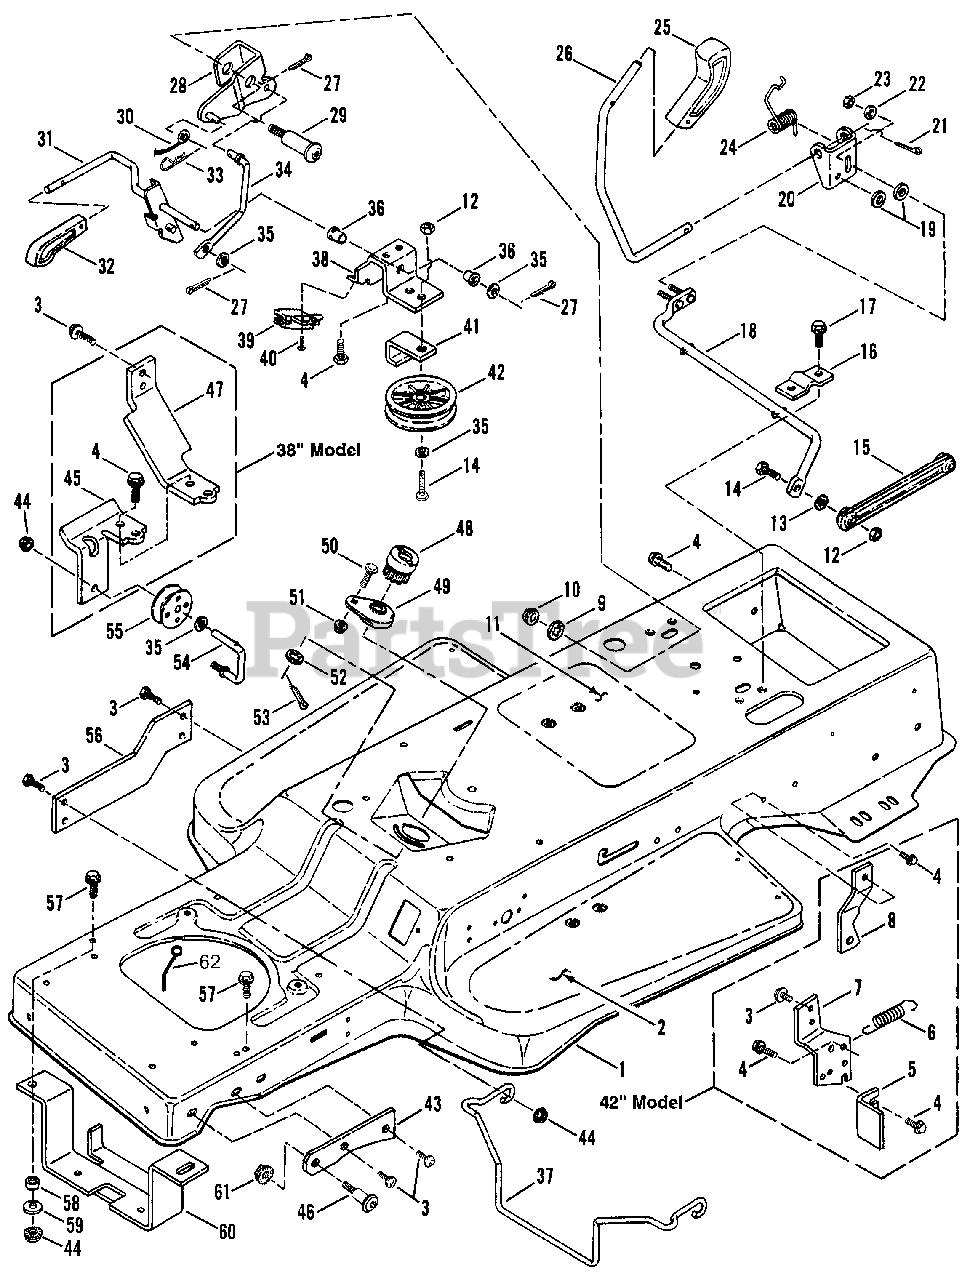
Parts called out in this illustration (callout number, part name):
1	FRAME, Blackhawk Tractor
2	FOOTPAD, Sandpaper
2	FOOTPAD, Deluxe
3	SCREW, 5/16-18 x 5/8" Truss Head (Torx)
4	SCREW, 5/16-18 x 5/8" Hex Washer Head
5	GUIDE, Cable
6	SPRING, Brake Return
7	BRACKET, Axle/Spool
8	BRACKET, Torque
9	WASHER, 1/2 Internal Tooth Lock
10	NUT, 1/2-13 Hex Flange Lock
11	DECAL, Instruction/Safety (Long)
11	DECAL, Instruction/Safety (Short)
12	NUT, 3/8-16 Hex Center Lock
13	SPACER
14	SCREW, 3/8-16 x 1 1/2" Hex Head Cap
15	LINK, Shift Lever
16	CLIP, Shift Lever
17	SCREW, 5/16-18 1 1/4" Self-Tap.
18	ASSEMBLY, Shift Lever (Lower)
19	WASHER, 1/4 Internal Tooth Lock
20	BRACKET, Shift Lever (Upper)
21	COTTER-PIN, 5/32 x 1"
22	WASHER, 1/4 Flat
23	NUT, 1/4-20 Hex Nyloc
24	SPRING, Shift Lever
25	KNOB, Deck Lift Lever
26	LEVER, Shift
27	COTTER-PIN, 3/32 x 3/4"
28	WELDMENT, PTO Bellcrank
29	BOLT, 1/2-13 x 2 11/32" Shoulder
30	CABLE, Blade 20.5"
30	CABLE, Blade 19.75"
31	WELDMENT, PTO Lever
32	KNOB, PTO Lever
33	PIN, Hair, 3/32 x 1 1/2"
34	ROD, PTO Link
35	WASHER, 3/8" Flat
36	BUSHING
37	GUIDE, Belt
38	SUPPORT, PTO Lever
39	SWITCH, Blade Engagement
40	SCREW, #10-24 x 1/2" Hex Washer Self-Tap (Torx)
41	GUIDE, Belt
42	PULLEY (3.5" V)
43	BRACKET, Hood Pivot
44	NUT, 5/16-18 Hex Flange Lock
45	BRACKET, Spool
46	BOLT, 3/8-16 x 1 1/4" Shoulder
47	BRACKET, Torque
48	GEAR, Steering Pinion
49	ASSEMBLY, Steering Adjuster
50	BOLT, 1/4-20 x 5/8" Short Neck Carriage
51	NUT, 1/4-20 Hex Flange Lock
52	WASHER, 1/2 Shim
53	COTTER-PIN, 1/8 x 3/4"
54	ROD, Spool Pivot
55	SPOOL
56	BRACE, Frame
57	BOLT, 5/16-18 x 1 1/4" Hex Washer Head
58	SPACER
59	WASHER, 13/32 x 3/4" Flat
60	WELDMENT, Belt Guide
61	NUT, 3/8-16 Hex Flange Lock
62	GUIDE, Belt
